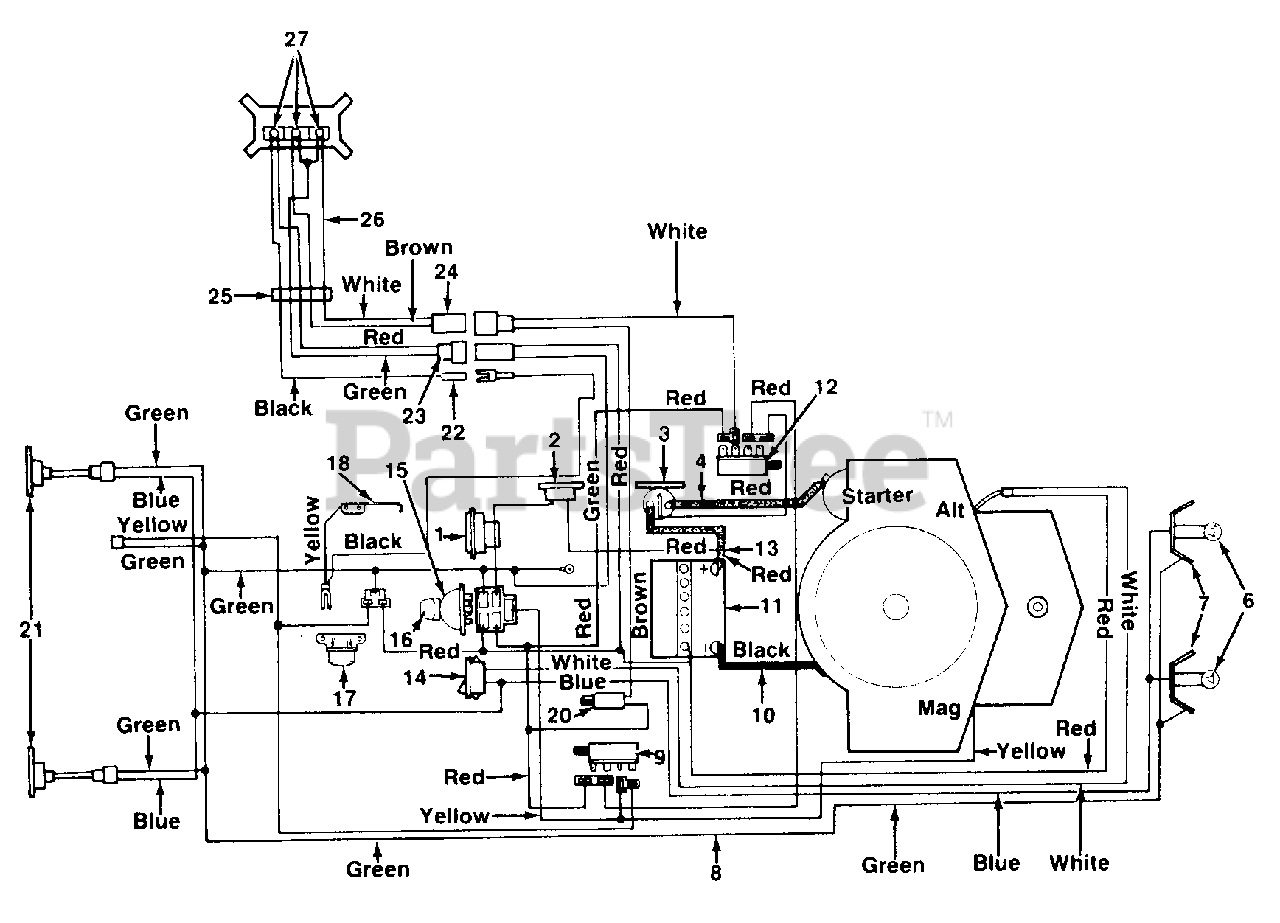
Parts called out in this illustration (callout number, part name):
1	Ammeter
2	Circuit Breaker
3	Solenoid
4	Wire
6	Bulb
7	Socket
8	Wire Harness
9	Safety Switch
10	6 Ga. Black Wire
11	Battery 12V
12	Safety Switch
14	Light Switch
15	Ignition Switch
16	Ignition Key
17	Relay
18	Spring Lever
20	Safety Switch
21	Taillight
22	Connector
23	Connector
24	Connector
25	Clamp
26	Wire Harness
27	Bulb
